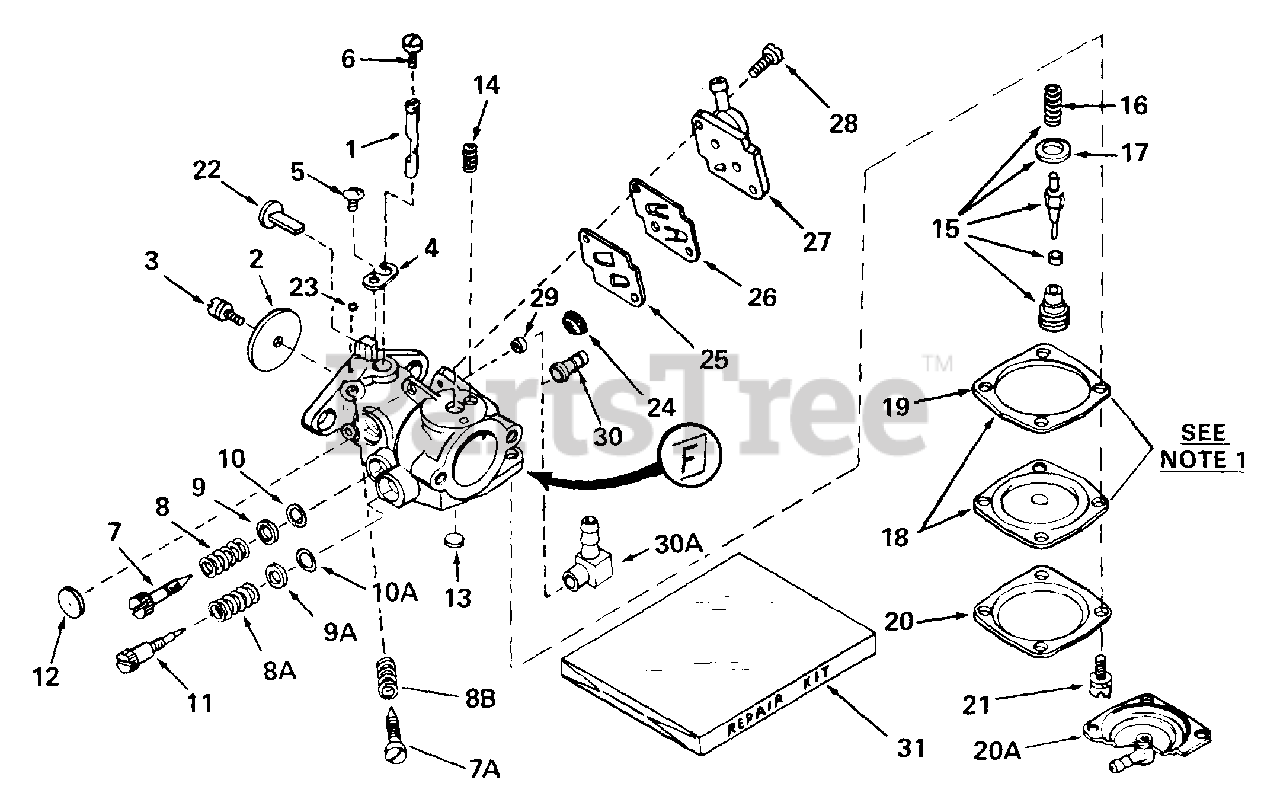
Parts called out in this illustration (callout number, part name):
1	"Shaft, Throttle
2	Shutter, Throttle
3	Screw, Shutter
6	Screw, Throttle lever
7	Screw, Idle adj.
8	Spring, Adj. screw
8A	Spring, Adj. screw
9	Washer, Adj. screw
9A	Washer, Adj. screw
10	"O" Ring, Adj. screw
10A	"O" Ring, Adj. screw
11	Screw, Main adj.
12	Plug, Welch
13	Plug, Welch
14	Spring, Choke positioning
15	Inlet Needle, Seat, Spring & Gasket A ssy.
16	Spring, Inlet needle
17	Gasket, Valve seat
18	Diaphragm Assy.
19	Gasket, Diaphragm
20	Cover, Diaphragm
21	Screw, Cover
24	Screen, Filter
25	Gasket
26	Valve, Flap
27	Cover Assy., Valve
28	Screw, Valve cover
31	Repair Kit
